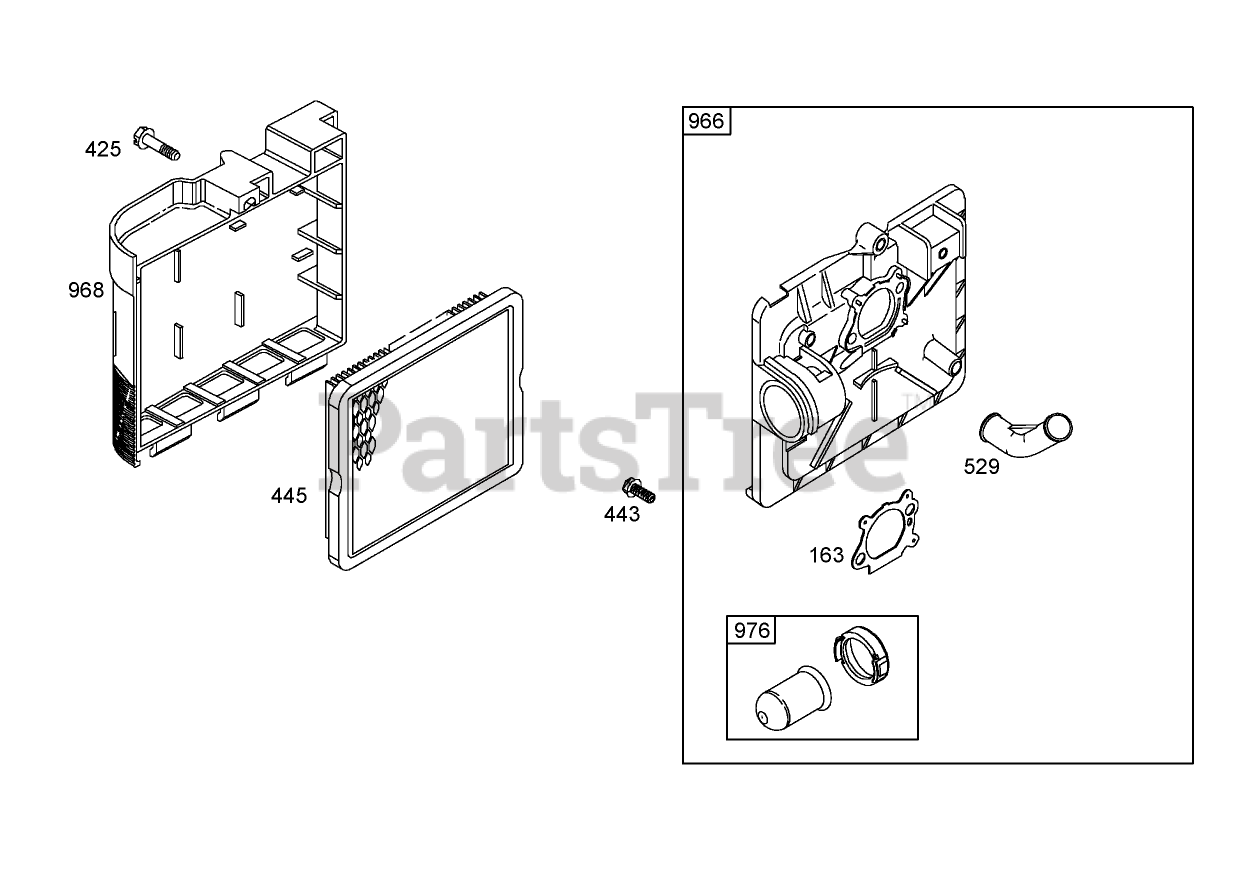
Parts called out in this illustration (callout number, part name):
163	Gasket-Cleaner, Air
425	Screw
443	Screw
445	Filter-Air Cleaner, Cartridge
529	Grommet
966	Base-Primer, Air Cleaner
968	Cover-Cleaner, Air
976	Primer-Carburetor
